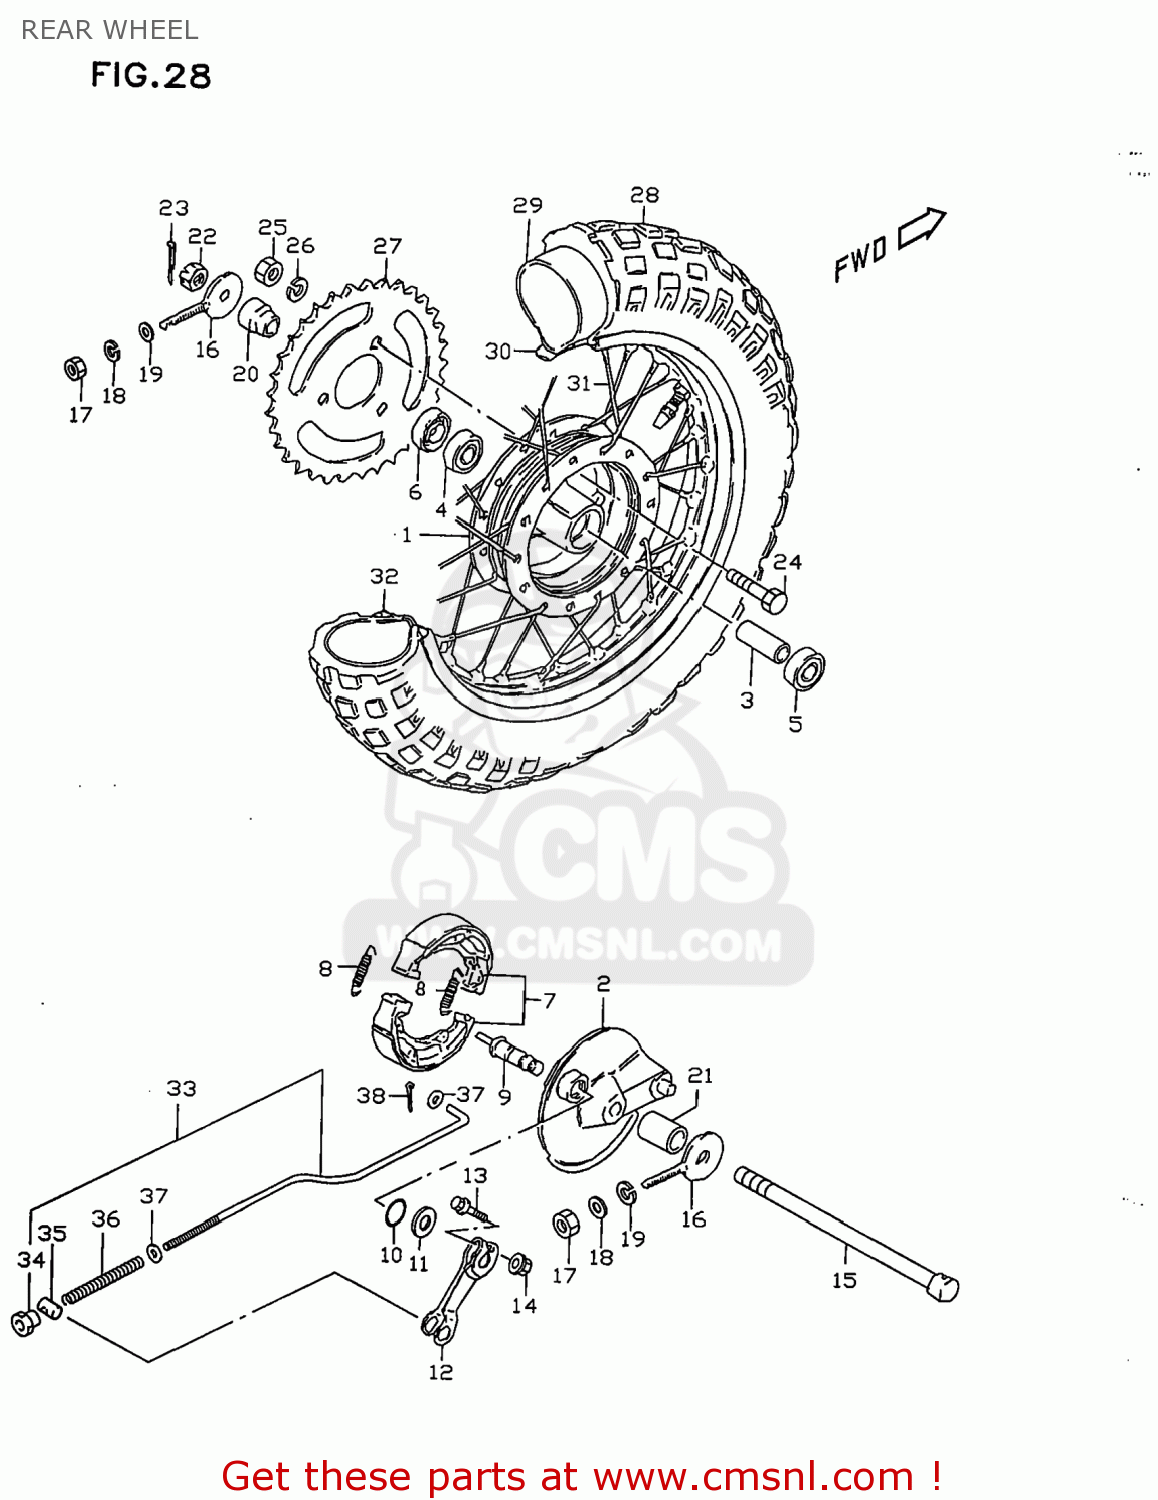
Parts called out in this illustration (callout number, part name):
1	HUB,RR WHEEL
2	PANEL,RR BRAKE ANCHOR
3	SPACER(10.2X16X55)
4	BEARING(10X26X8)
5	BEARING
6	SEAL,OIL(15X27X6)
7	SHOE & SPRING SET (NAS)
8	SPRING(L:35.8)
9	CAM,BRAKE
10	O RING(D:2.4,ID:9.6)
11	WASHER(10.5X18X1)
12	LEVER,RR BRAKE CAM
13	BOLT
14	NUT
15	AXLE,RR
16	ADJUSTER,CHAIN
17	NUT 6MM
18	LOCK WASHER
19	WASHER
20	SPACER,RR AXLE,L
21	SPACER,RR AXLE,R
22	NUT
23	PIN 20X20
24	BOLT(8X36)
25	NUT
26	WASHER,LOCK
27	SPROCKET,RR
28	TIRE
29	TUBE,INNER
30	PROTECTOR,INNER TUBE
31	SPOKE SET,RR
32	RIM,WHEEL
33	ROD ASSY,RR BRAKE
34	NUT
35	PIN,10X19
36	SPRING
37	WASHER
38	PIN
